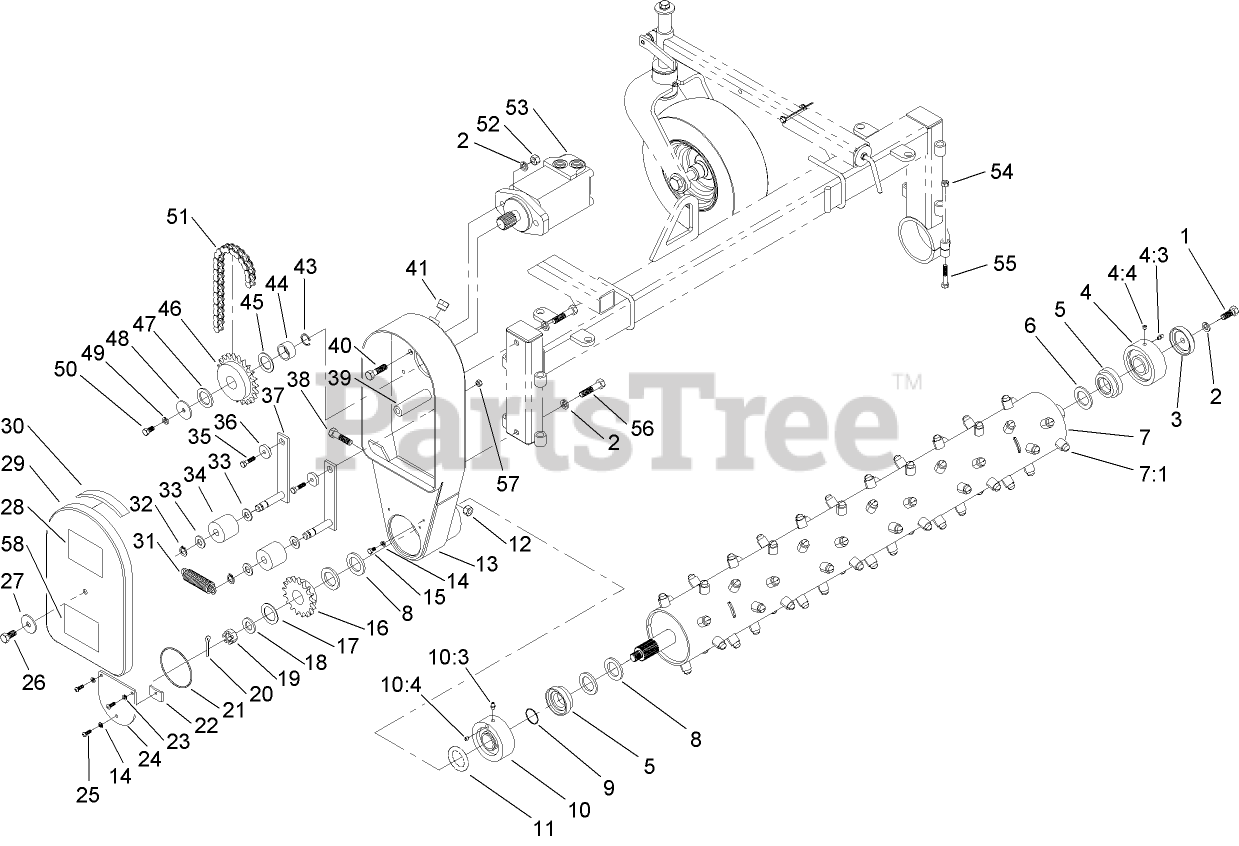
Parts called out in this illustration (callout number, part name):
1	SCREW-HH
2	WASHER-LOCK
3	CAP-BEARING
4	IDLE BEARING ASM
4:3	FITTING-GREASE
4:4	SCREW-SET, HSH
5	COLLAR-BEARING
6	BUSHING-MACHINED
7	ROLLER-TOOTH, CARBIDE
7:1	TOOTH-RAKE
8	SPACER-FLAT
9	O-RING
10	DRIVE BEARING ASM
10:3	FITTING-GREASE
10:4	SCREW-SET, HSH
11	O-RING
12	NUT-LOCK
13	CASE-CHAIN
14	WASHER-ORING
15	SCREW-HH
16	SPROCKET-17 TOOTH
17	BUSHING-MACHINED
18	WASHER-WHEEL
19	NUT-HEX, SLOTTED
20	PIN-COTTER
21	O-RING
22	TAB-COVER
23	WASHER-LOCK
24	COVER-LOWER, CHAIN
25	SCREW-HSBH
26	SCREW-HH
27	WASHER-THRUST
28	DECAL
29	COVER-CHAIN
30	SEAL-COVER
31	SPRING-EXTENSION
32	RING-RETAINING
33	WASHER-FLAT
34	ROLLER-TENSIONER
35	SCREW-HH
36	BUSHING-PIVOT
37	ARM-TENSIONER
38	SCREW-HH
39	ROD-COVER, SPACER
40	SCREW-HH
41	PLUG-BREATHER
43	RING-SNAP, EXTERNAL
44	COLLAR-SPROCKET
45	BUSHING-MACHINED
46	SPROCKET-22 TOOTH
47	BUSHING-MACHINED
48	WASHER
49	WASHER-LOCK
50	SCREW-HH
51	CHAIN-ROLLER
52	NUT-HH
53	HYD MOTOR ASM
54	NUT-HEX
55	SCREW-HH
56	SCREW-HH
57	NUT-LOCK, CONE
